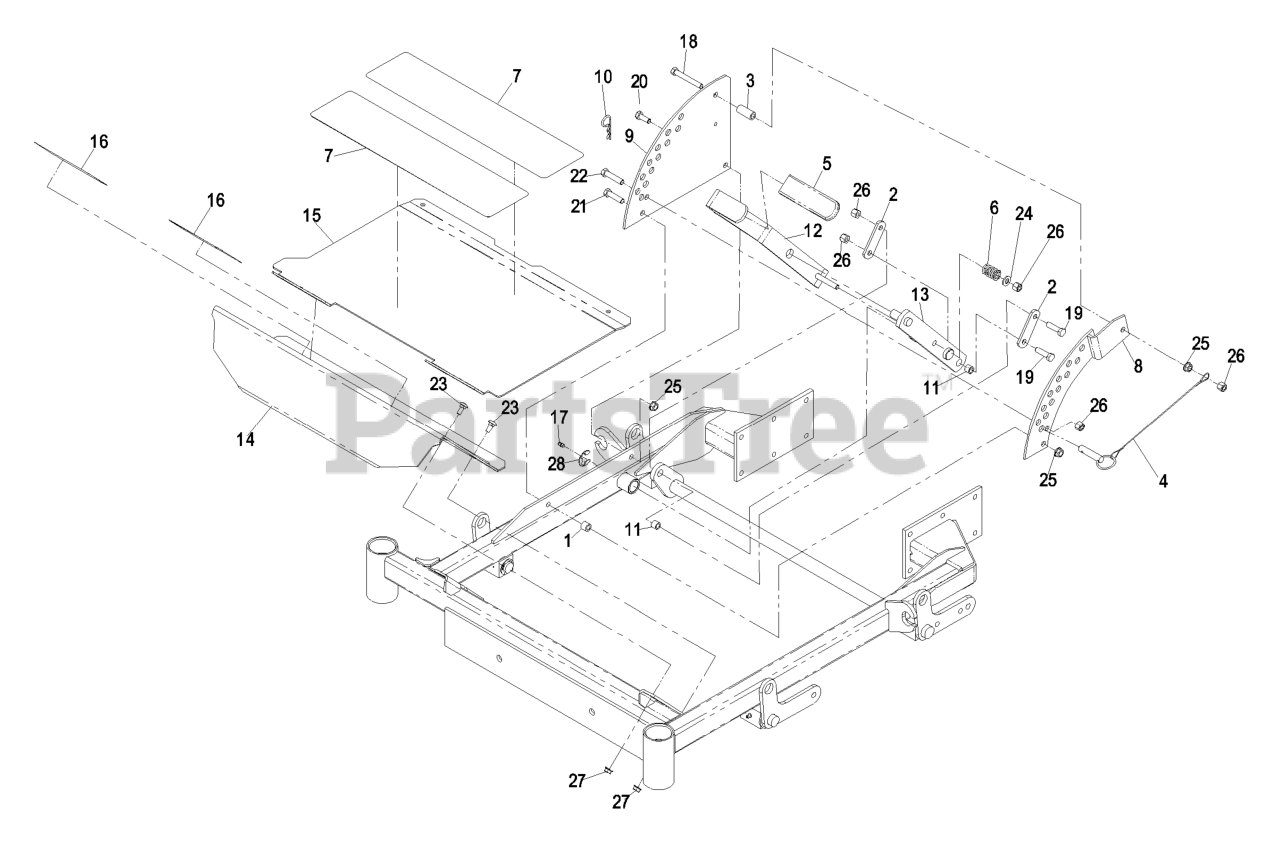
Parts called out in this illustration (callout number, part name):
1	BUSHING-LEVER, LIFT
2	ARM-LIFT, DECK
3	BUSHING-LEVER, LIFT
4	PIN-HITCH (W/LANYARD)
5	GRIP-LEVER, LIFT
6	SPRING-COMPRESSION
7	PAD-ANTISKID
8	PLATE-LIFT, DECK
9	PLATE-LIFT, DECK
10	PIN-COTTER
11	BUSHING
12	ASM, LIFT LEVER / GRIP
13	WLD, DECK LIFT ARM-LHP
15	ASM,FLOORPAN
16	PAD-ANTI SKID
17	FITTING-GREASE
18	SCREW-HH
19	SCREW-HH
20	SCREW-HH
21	SCREW-HH
22	SCREW-HH
23	BOLT-CARR
24	WASHER-FLAT
25	NUT-HHF, WHIZ
26	NUT-LOCK, NI
28	RING-RETAINING, EXT
